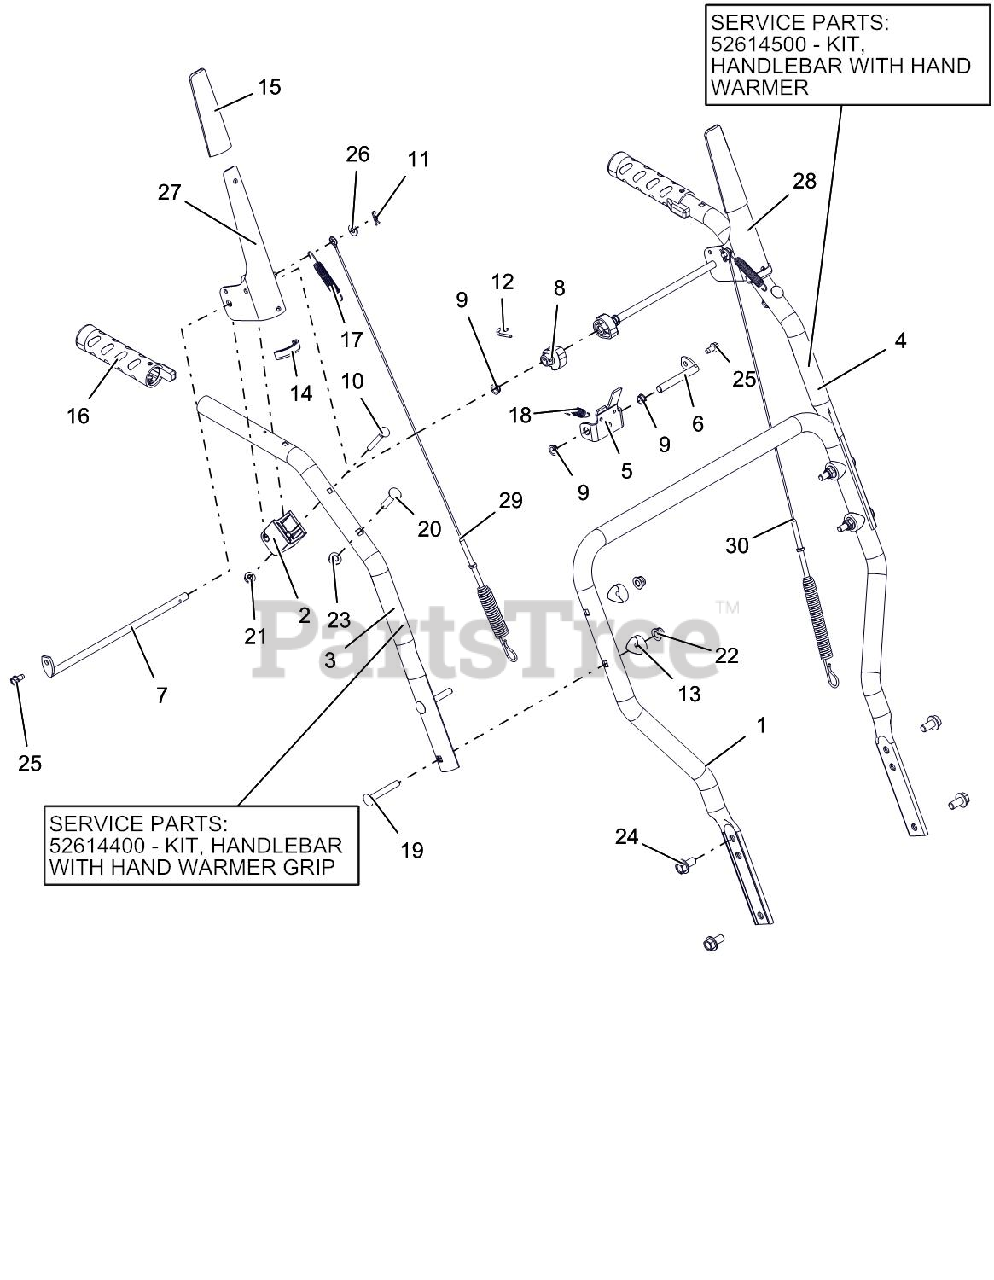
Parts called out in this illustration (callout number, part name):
1	HANDLEBAR, LOWER
2	BLOCK, CLUTCH PADDLE
3	HANDLEBAR, UPPER - RH
3	KIT, HANDLEBAR HW RH
4	HANDLEBAR, UPPER - LH
4	KIT, HANDLEBAR HW LH
5	BRACKET, INTERLOCK ARM
6	ROD, PIVOT - INTERLOCK
7	ROD, PADDLE MOUNT - PRO
8	CAM, INTERLOCK
9	BUSHING, POLYLINER-.38 SNAPIN
10	BLT-RDHDXLSQNK .25-20X2.0 G5YZ
11	PIN-HAIR INT .06X.18X.77
12	PIN, SPRING CLIP
13	SPACER, HANDLEBAR
14	EDGING, CLUTCH PADDLE - 2.00"
15	SLEEVE, CLUTCH PADDLE-GRAY
16	KIT, HANDWARMER - W/GLUE
17	SPRING, EXTENSION
18	SPRING-EXT .047X.438X1.45
19	@BLT-RDHDSQNK .31-18X2.25 G5YZ
20	@BLT-RDHDSQNK .31-18X1.50 G5YZ
21	@NUT-LK-CTR-FLG .25-20 YWZC
22	@NUT-LK-NYL-FLG .31-18 YWZC
23	@NUT-LK-TOP-FLG .31-18 YWZC
24	BLT-SERHFWH .38-16X.75 YWZC
25	SCR-TAP .25-20X.50 HWH TR YWZ
26	@WSHR-FL-STL.281X.62X.065 YWZC
27	LEVER, CLUTCH-RH
28	LEVER, CLUTCH-LH
29	CABLE, AUGER (DELUXE & PRO)
30	CABLE, UPPER TRACTION
